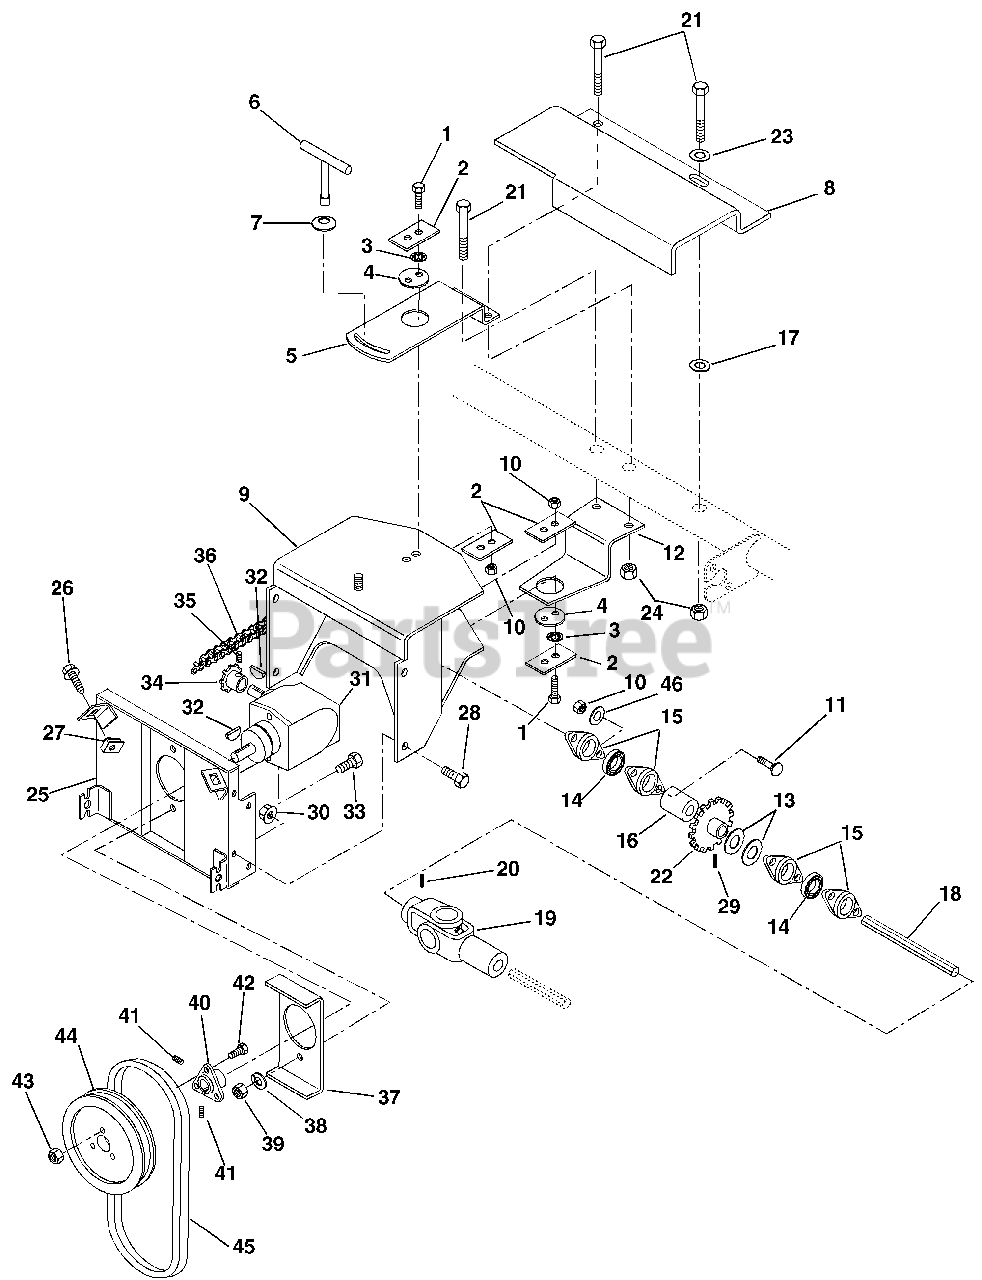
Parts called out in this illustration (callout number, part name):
1	@BLT-HEX .31-18X1.25 GR5 YWZC
2	RETAINER
3	@WSHR-LK-EXT.326X.599X.031YWZC
4	PIVOT CENTER
5	PLATE, TOP MOUNT
6	T-LOCK HANDLE
7	WASHER, CUPPED SERRATED, .375
8	GUARD, SHAFT
9	FRAME, ADAPTOR
10	@NUT-LK-CTR .31-18 YWZC
11	@BLT-RDHDSQNK .31-18X.75 G5YZ
12	PLATE, BOTTOM MOUNT
13	WSHR-FL-STL 1.015X1.500X.125
14	BRG-BALL .884HEXX52MMX1.07
15	BEARING FLANGE
16	SPACER 1.006X1.307X.500
17	WSHR-FL-STL .390X.88X.18 YWZC
19	JOINT, UNIVERSAL
20	PIN-ROLL .188X1.50
21	@BLT-HEX .38-16X3.25 GR5 YWZC
22	SPROCKET
23	@WSHR-FL-STL.406X.812X.065 YWZ
24	@NUT-LK-CTR .38-16 YWZC
25	PLATE, MOUNTING
26	BLT-SERHFWH .38-16X.75 YWZC
27	NUT-RETNR .38-16 TINRMAN
28	@BLT-HEX .38-16X.75 GR5 YWZC
29	PIN-ROLL .188X1.75
30	@NUT-LK-CTR .38-16 YWZC
31	GEAR BOX ASSEMBLY
32	KEY-WDRF .188X.75X.313 SAE 9
33	@BLT-HEX .38-16X1.25 GR5 YWZC
34	SPROCKET
35	SCR-SET .25-20X.38 SKHCUPNL OH
36	CHAIN
37	PLATE, STIFFENER
38	@WSHR-LK .38X.094 REG YWZC
39	@NUT-HEX .38-16 YWZC
40	HUB ASSEMBLY
41	SCR-SET .31-18X.38 SKHCUPDL
42	BLT-SERRDHD SL .31-18X.75 YZ
43	@NUT-SPNLK-FLG .312-18 YWZC
44	PLY-V 9.0 X 1.25 3BLT
45	V-BELT, 4L-RAW EDGE
46	@WSHR-FL-STL.38X.875X.083 YWZC
